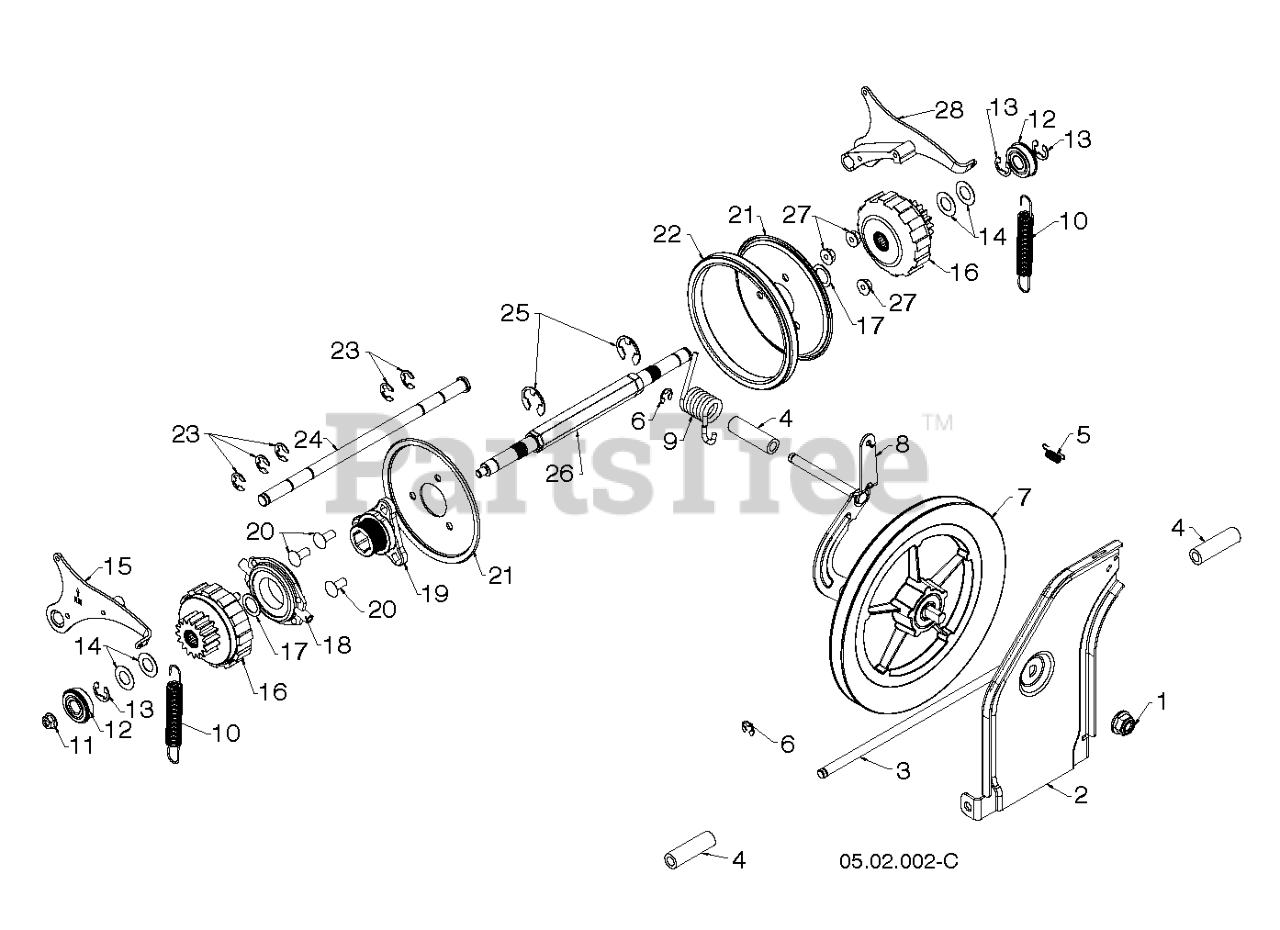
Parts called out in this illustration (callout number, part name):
1	NUT, 1/2-13 HEX FLG NYLOC ZD
2	PLATE.SWING.FRICTION PULLEY.47
3	ROD.TIP.PLATE
4	SPACER YOKE, TORSION SPRING
5	SPRING LATCH
6	E-RING LT
7	PULLEY.FRICTION.DISC.COMBO
8	BRACKET.YOKE.ASSEMBLY.479
9	SPRING TORSION DRIVE
10	SPRING EXTENSION PS
11	NUT.HEX.FLANGE.LOCK.5/16-18
12	BEARING 9/16 ID. SNR
13	RING.RETAINING.1622-2RSNR.CLER
14	WASHER FLAT.637IDX1.00ODX21GA
15	PAWL.ASM.RH.SNOW
16	GEAR.ASM.PLANETARY
17	WASHER FLAT.59IDX1.065ODX25GA
18	TRUNNION BEARING ASSY
19	HUB.RUBBER.WHEEL
20	Bolt, Carriage 5/16-18 UNC x 3/4 (AYP part number)
21	PLATE.RUBBER.WHEEL.BLACK
22	RING RUBBER
23	CLIP E-RING_.500 SHAFT
24	ROD ROD, PAWL ROD
25	E-Ring Truarc #5133-87 (AYP part number)
26	SHAFT SHAFT, PWR STR SHAFT
27	NUT.LOCK.5/16-18
28	PAWL.ASM.LH.SNOW
